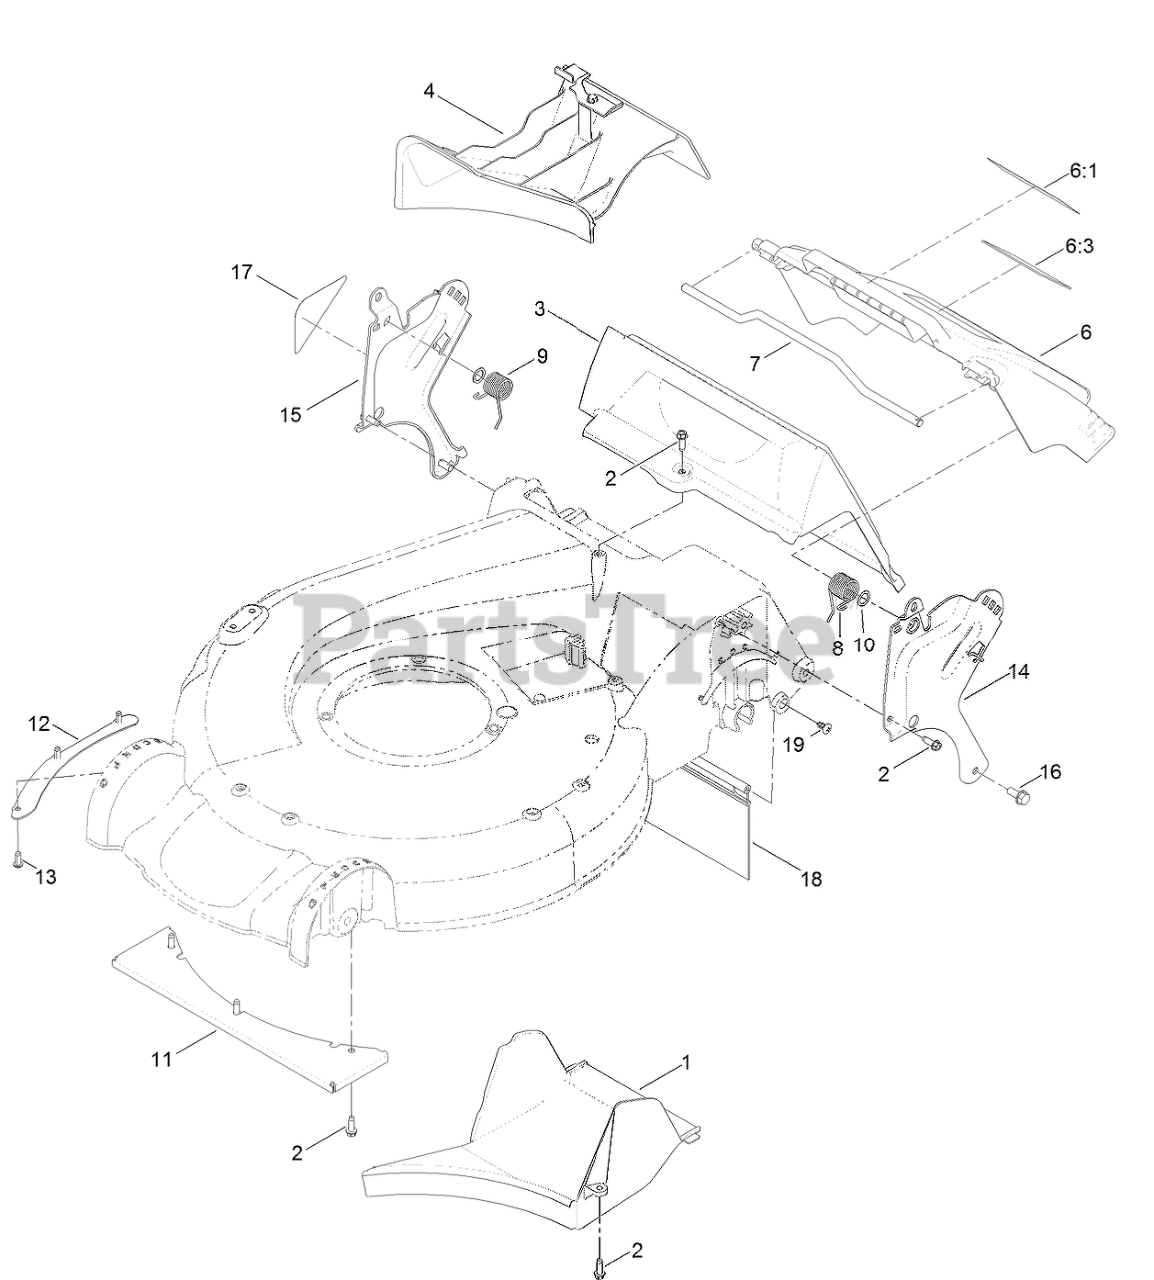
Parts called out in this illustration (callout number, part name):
1	TUNNEL-DISCHARGE
2	SCREW-HWHTF
4	MULCH PLUG ASM
6	REAR DOOR ASM
6:1	DECAL-WARNING
6:3	DECAL-WARNING
7	ROD-DEFLECTOR
8	SPRING-TORSION
9	SPRING-TORSION
10	WASHER-NYLON
11	PLATE-COVER, FRONT
12	SHEET-LIP
13	SCREW
14	BRACKET-HANDLE, LH
15	BRACKET-HANDLE, RH
16	SCREW-HWHTF
17	DECAL-INSTRUCTION
18	SHIELD-TRAILING
19	SCREW-PTH
